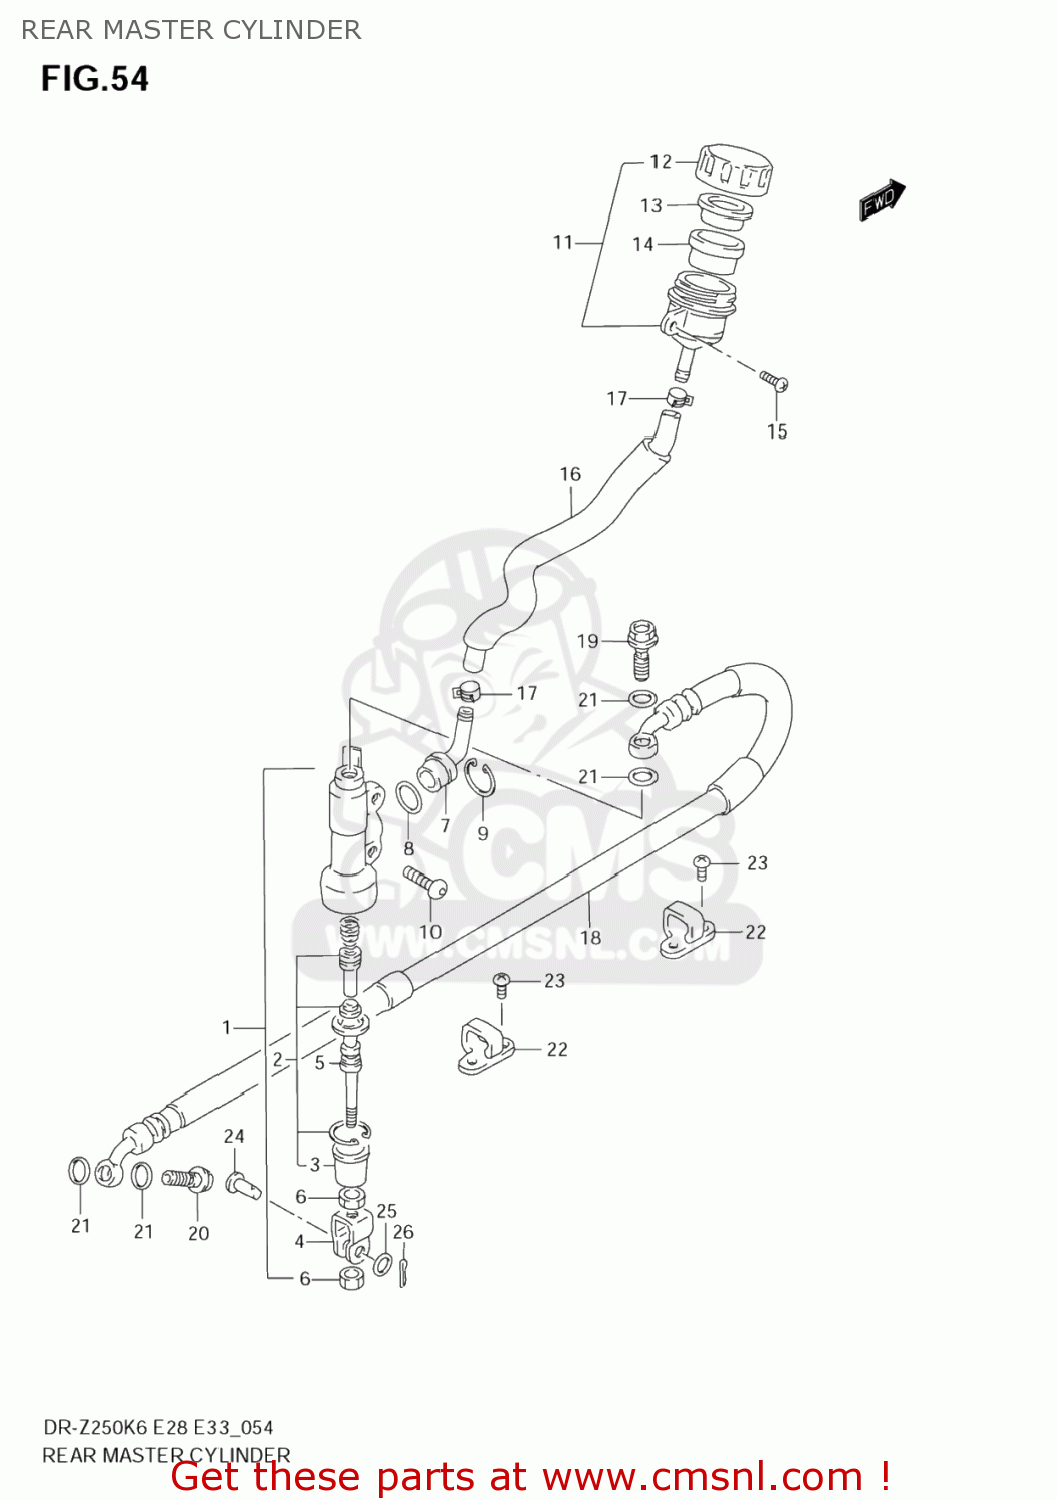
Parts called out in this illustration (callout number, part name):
1	CYLINDER ASSY,RR MASTER
2	PISTON/CUP SET
3	BOOT
4	YOKE
5	ROD,PUSH
6	NUT
7	CONNECTOR
8	O RING
9	CIRCLIP
10	SCREW(6X16)
11	TANK ASSY,RESERVOIR
12	CAP
13	PLATE
14	DIAPHRAGM
15	SCREW 6X12
16	HOSE,RESERVOIR TANK
17	CLIP
18	HOSE, REAR BRAKE
19	BOLT UNION
20	BOLT UNION
21	WASHER(10X15X1.5)
22	GUIDE,RR BRAKE
23	SCREW
24	PIN(8X20)
25	WASHER (8.5X14X1.6)
26	PIN
